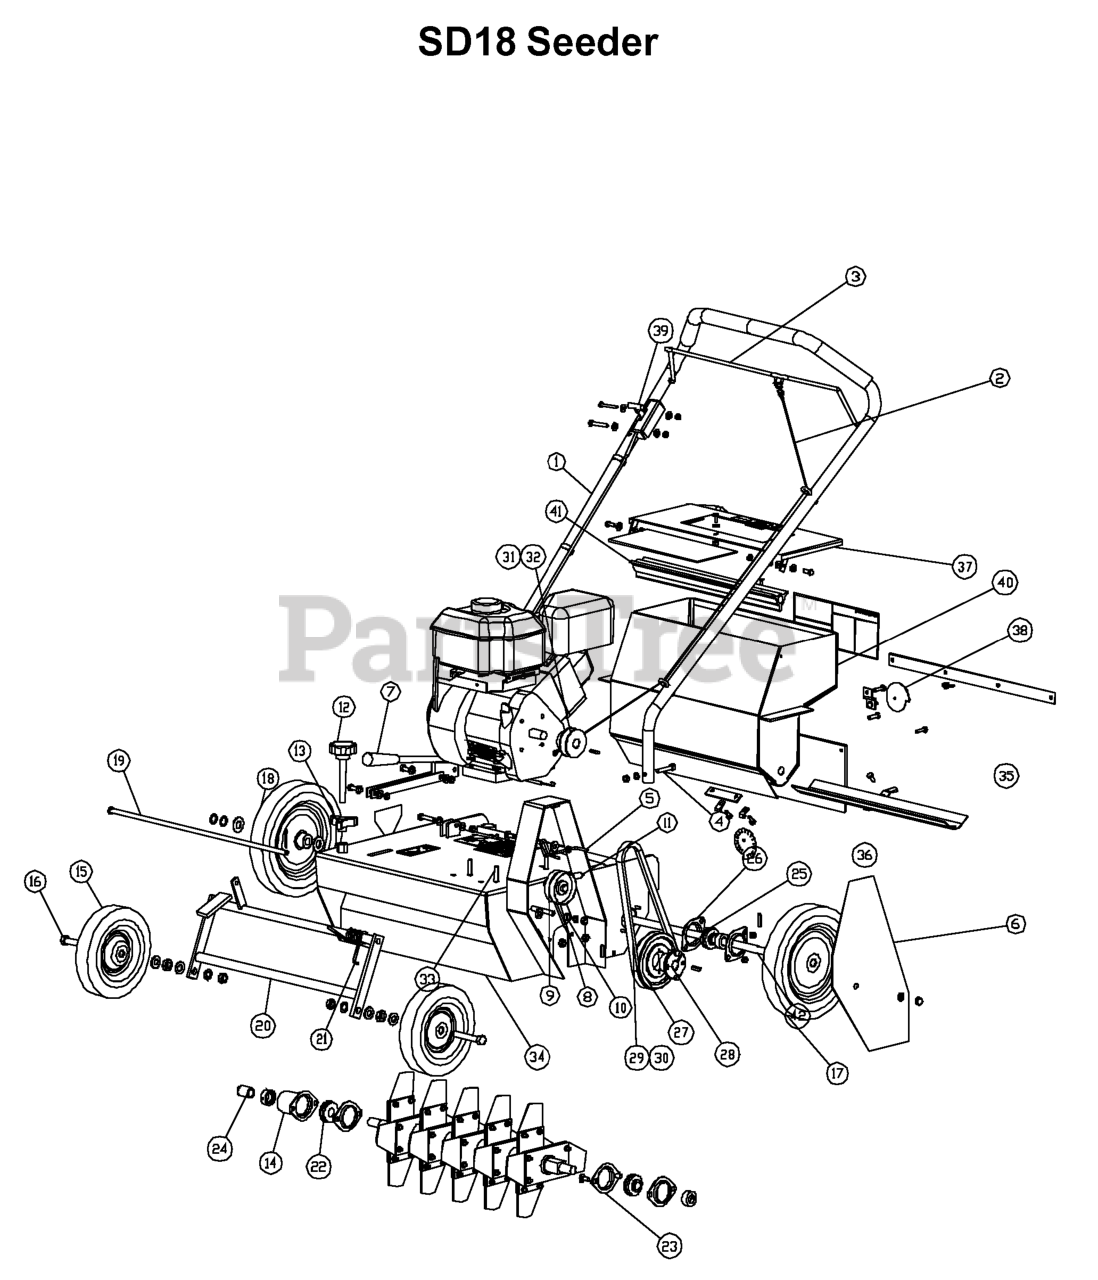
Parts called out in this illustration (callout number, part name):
1	KIT, HANDLE ASSY
2	CLUTCH CABLE
4	BOLT KIT
5	BELT KEEPER KIT
6	BELT GUARD KIT ORN
7	DEPTH LEVER ASSY
8	IDLER ASSY KIT
9	PULLEY
10	MTG ARM, IDLER PULLEY
11	SPRING
12	DEPTH ADJUSTMENT KNOB
13	3-PRONGED LOCK DEPTH
14	ROTOR GUARD
15	WHEEL
16	BOLT KIT
17	KIT, WHEEL
18	KIT, WHEEL, RIGHT REAR
19	LIFT ARM ROD KIT
20	LIFT ARM ASSY OR
21	TORSION SPRING
22	BEARING
23	STAMPING KIT
24	ROTOR CAP
26	STAMPING KIT
27	V-PULLEY
28	BUSHING KIT
29	V-BELT
30	V-BELT
31	V-PULLEY
32	V-PULLEY
33	ENGINE BOLT KIT
35	DEFLECTOR KIT
36	DEFLECTOR, NEOPRENE
37	KIT, HOPPER LID
38	DIAL GAUGE KIT
39	KIT, PUSH-PULL CONTROL
40	SEED HOPPER
41	AGITATOR BAR
44	Kit Decal SD18 Seeder
